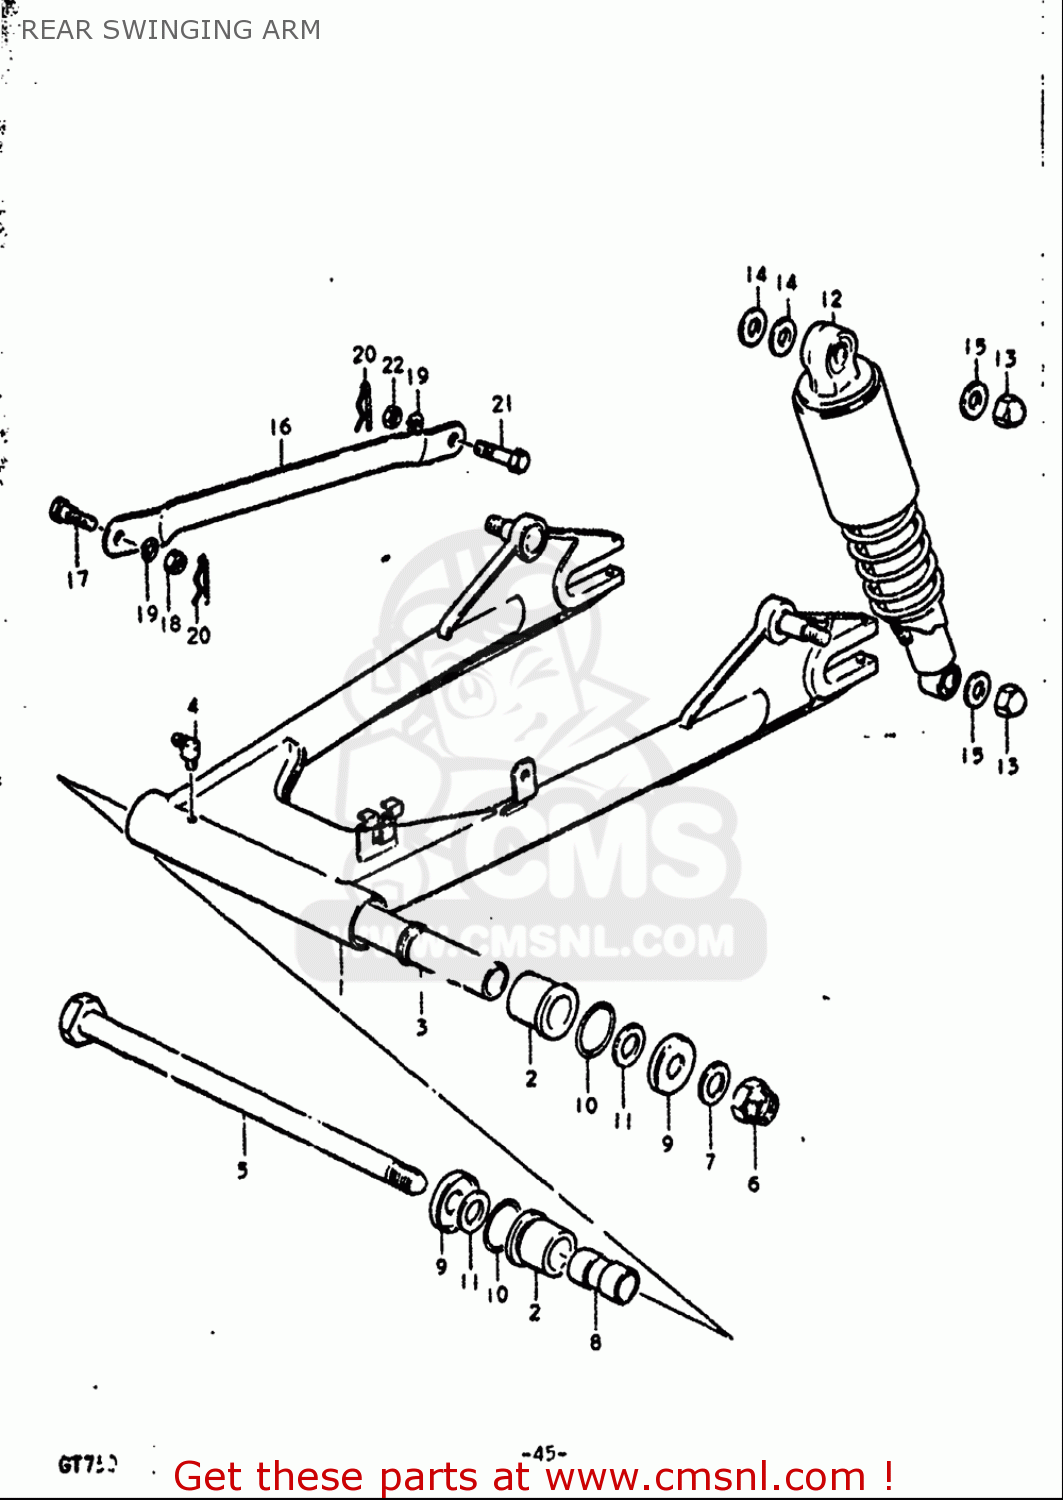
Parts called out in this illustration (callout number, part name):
2	BUSH
4	NIPPLE,GREASE
5	SHAFT,REAR SWING ARM
7	WASHER
8	SPACER
9	COVER
10	O RING(D:3,ID:29.5)
11	WASHER(14.5X29X2.3)
13	NUT
14	WASHER
15	WASHER(10.5X28X2.3)
18	NUT
19	WASHER,LOCK
20	CLIP
21	BOLT(10X31)
22	NUT
23	CLIP
